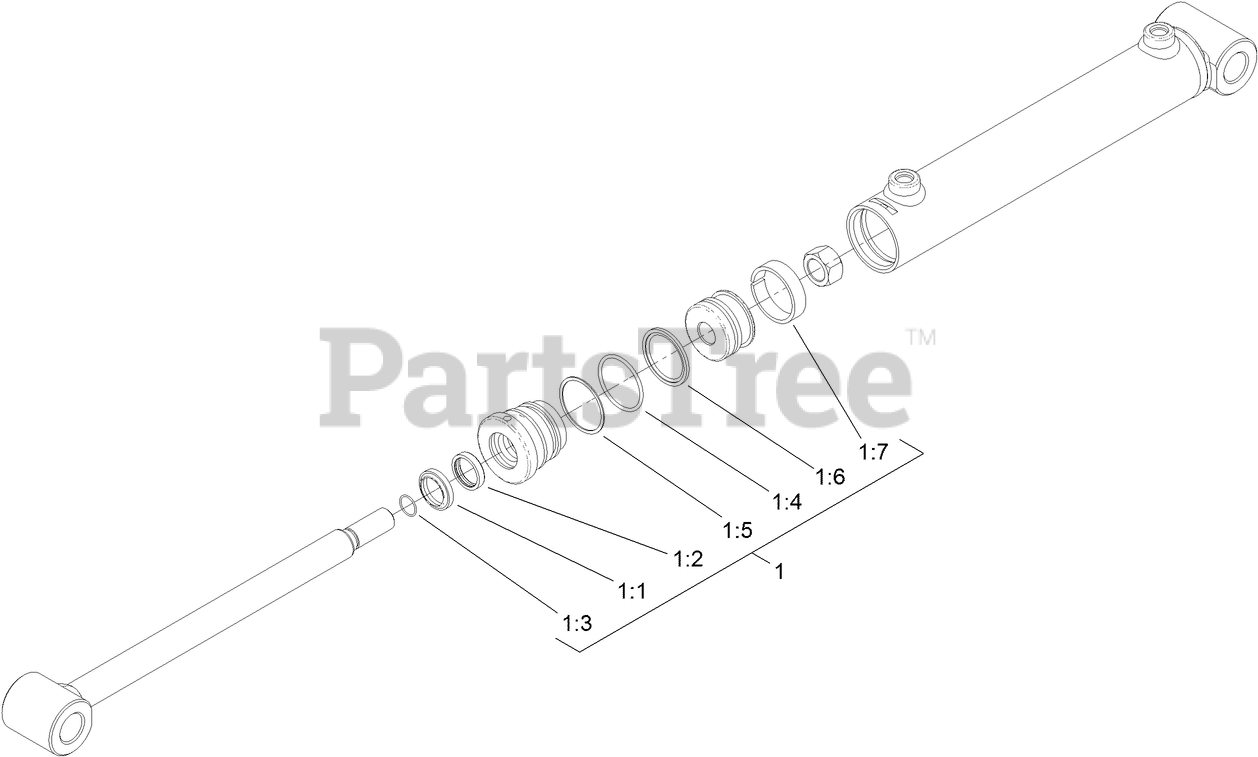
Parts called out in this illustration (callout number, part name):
1	SEAL KIT
1:1	WIPER
1:2	U-CUP
1:3	O-RING
1:4	O-RING
1:5	BACK-UP RING
1:6	CAPSEAL
1:7	WEAR RING
